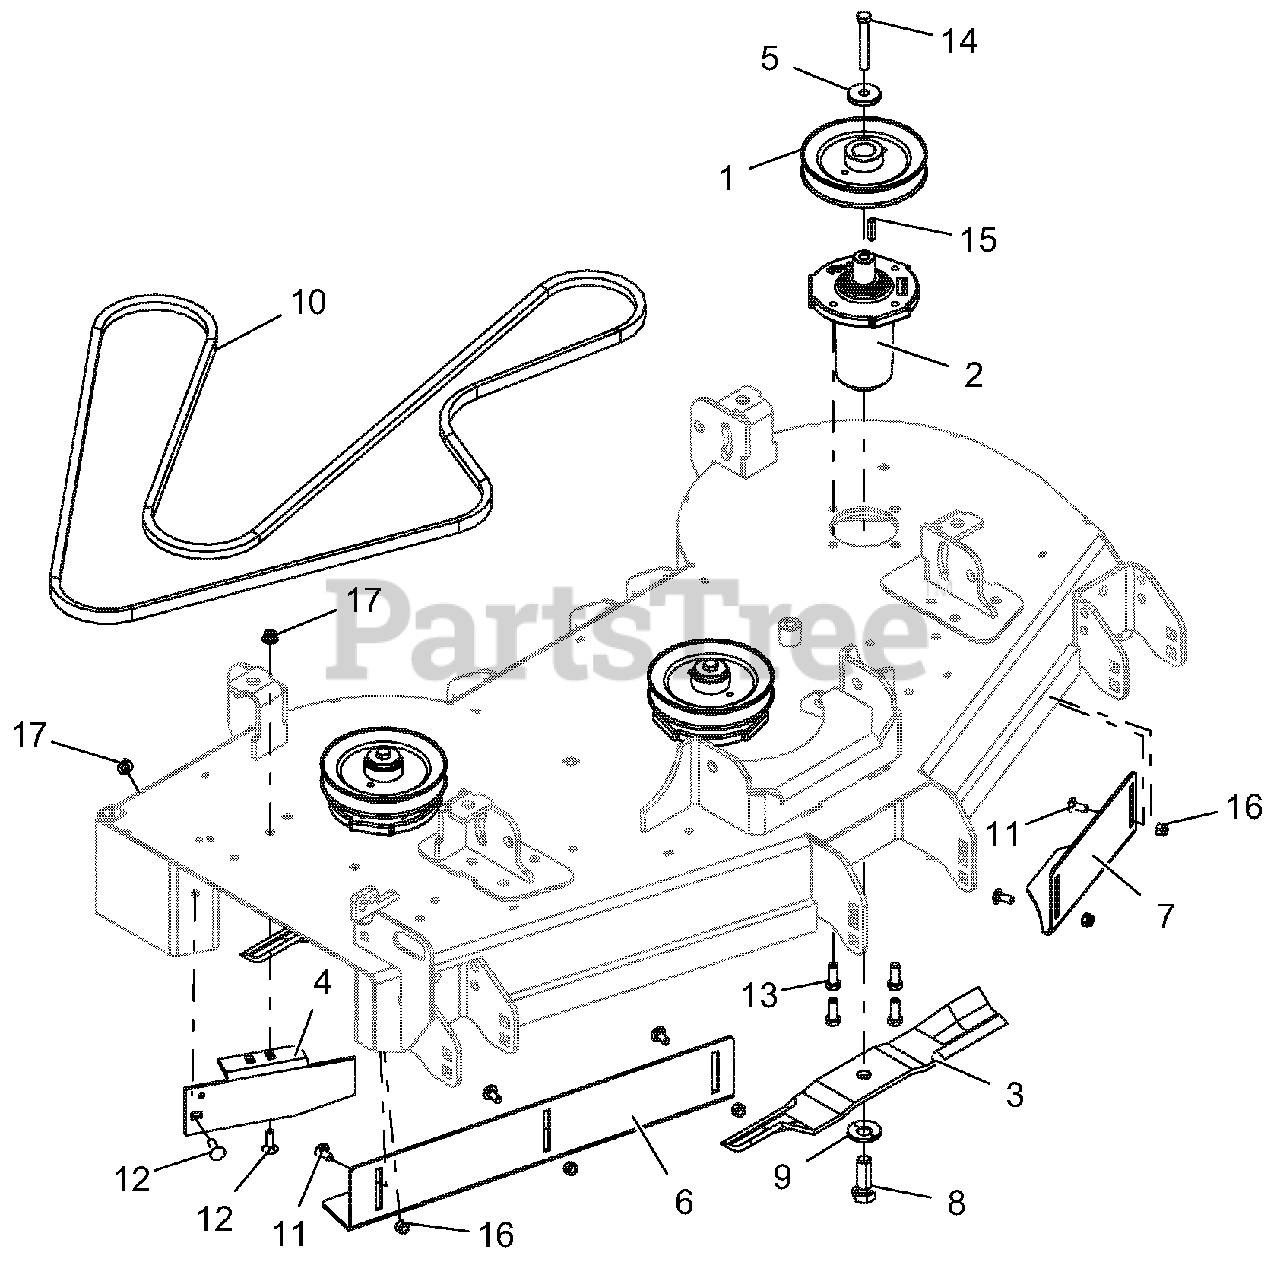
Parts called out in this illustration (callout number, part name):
1	PULLEY, V-1.00 ID X 5.75 OD
2	SERVICE, ASM SPINDLE- DUCTILE
3	BLADE, 16.19" MOWER (HI-LIFT)
4	BAFFLE, 44-48" SIDE DISCHARGE
5	RETAINER, SHEAVE SPINDLE
6	BAFFLE, 48" RH VACUUM
7	BAFFLE, 44/48" LH VACUUM
8	BLT, HEX .62-18X1.75 GR8 YWZC
9	WSHR, BLVL .63X1.625X.14
10	V-BELT, B SECTION RAW EDGE
11	BLT-RDHDSQNK .31-18X.75 G5 YWZC
12	BLT-RDHDSQSHNK .31-18X1.00 G5 Y
13	BLT-HEX .38-16X1.00 GR5 YWZC EP30
14	BLT-HEX .38-16X2.75 GR8 YWZC
15	KEY-SQ .250X.250X1.00 RC 40-50
16	NUT-LK-NYL .312-18 YWZC
17	NUT-LK-NYL-FLG .31-18 YWZC
